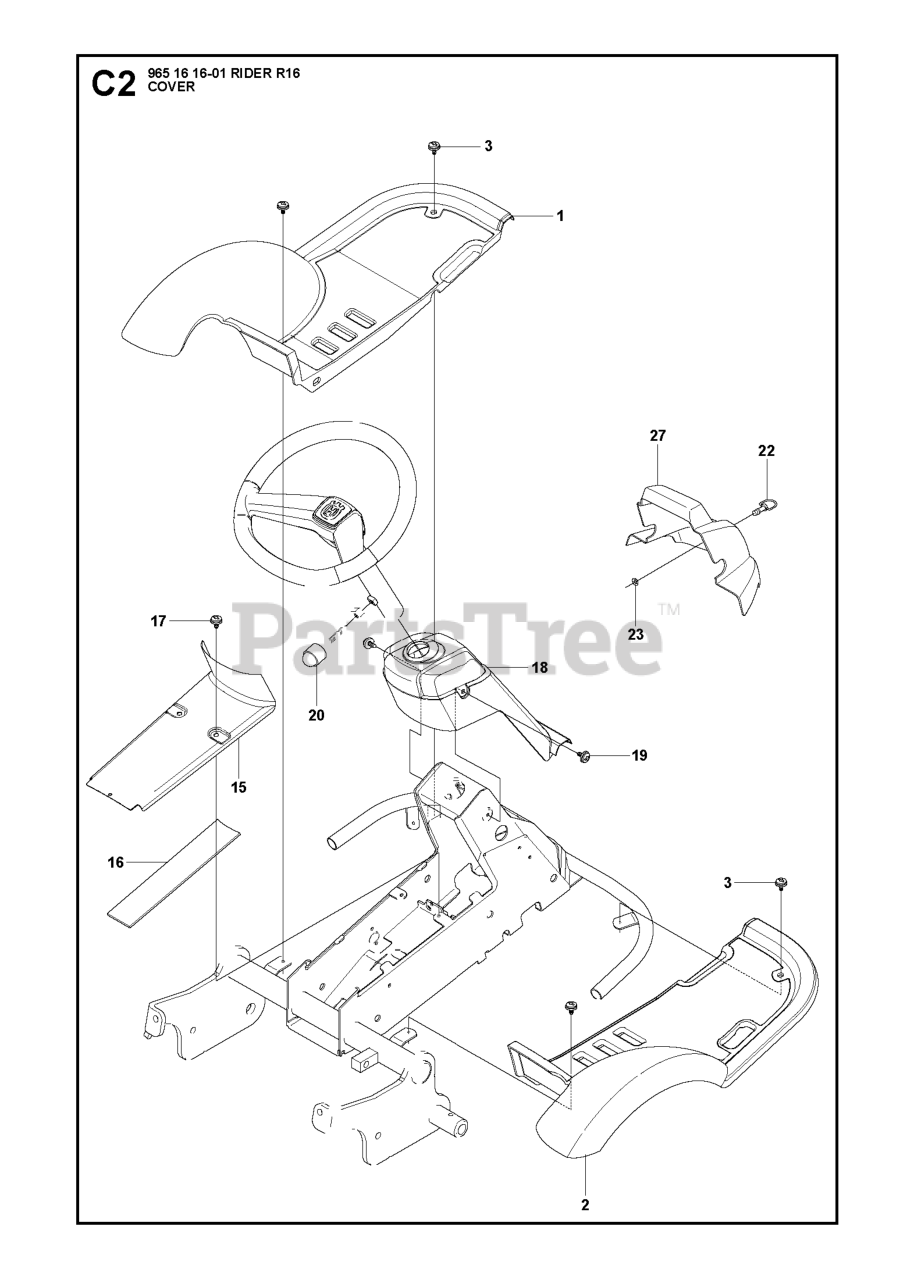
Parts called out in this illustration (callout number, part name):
1	FOOT PLATE
2	FOOT PLATE
20	PROTECTIVE COVER
22	BOLT
